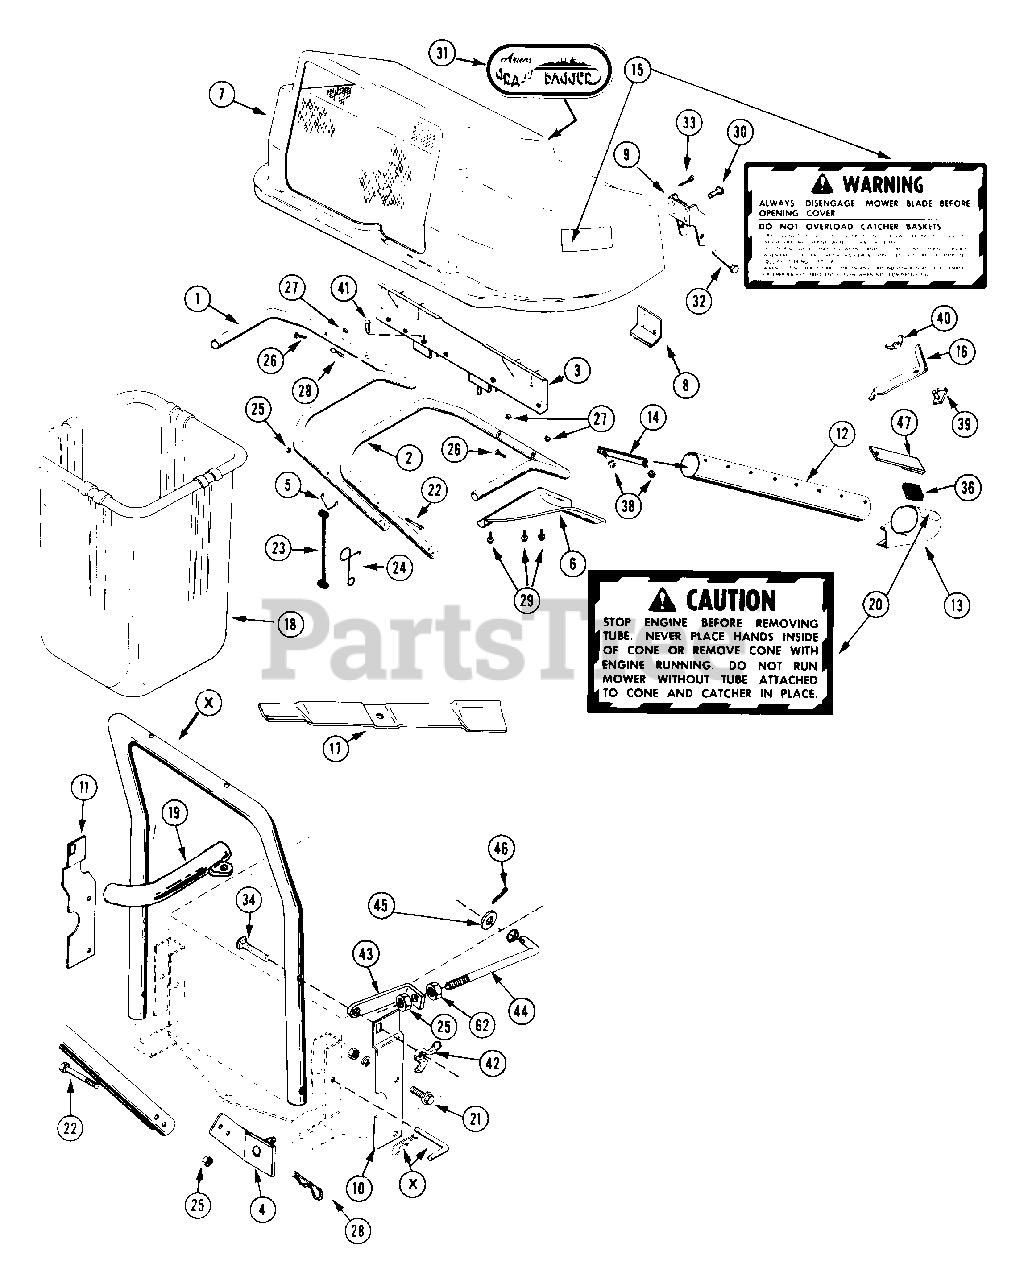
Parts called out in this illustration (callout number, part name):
1	TUBE L.H. SUPPORT
2	TUBE R.H. SUPPORT
4	LOWER MOUNTING BRACKET
6	SUPPORT
7	GRASS CATCHER COVER ASSEMBLY
8	RETAINER
10	STABILIZER R.H.
11	STABILIZER L.H.
12	TUBE BLANK
13	CONE ASSEMBLY
15	WARNING DECAL
16	STRAP CONE
17	MOWER BLADE
19	EXHAUST PIPE EXTENSION
20	CAUTION DECAL
21	BLT-SERHFWH .31-18X.50 PL
22	BLT-HEX .25-20X2.25 GR2
23	BATTERY STRAP
24	HOOK
25	NUT-LK-CTR .250-20 PL
26	SCR-MCH .31-18X1.50 CROVCNTRS
27	NUT-LK-NYL.312-18 PL
28	PIN-HAIR INT .08X.38X1.42 YWZC
29	BLT-SERHFWH .25-20X.50 PL
30	BLT-SCRHFWH .25-20X.62 PL
31	DECAL-GRASS BAGGER
32	CLEVIS PIN
33	PIN-COTR .06X.50
34	BLT-CRVD-HD .31-18X1.44 YWZC
35	WING NUT, .312-18
36	HOOK FASTENER
37	RVT-TBLR .187X.281 OV ST PL
38	NUT-LK-FLG .250-20 PL
39	CLIP CONE
40	NUT-WING W/INSERT .312 - 18
41	CLEVIS PIN
42	NUT-HEX .250-20 PL
43	BRACKET
45	WSHR-FL-STL .265X.500X.087 PL
46	PIN-HAIR INT .08X.18X1.18
47	ATTACHING STRAP
